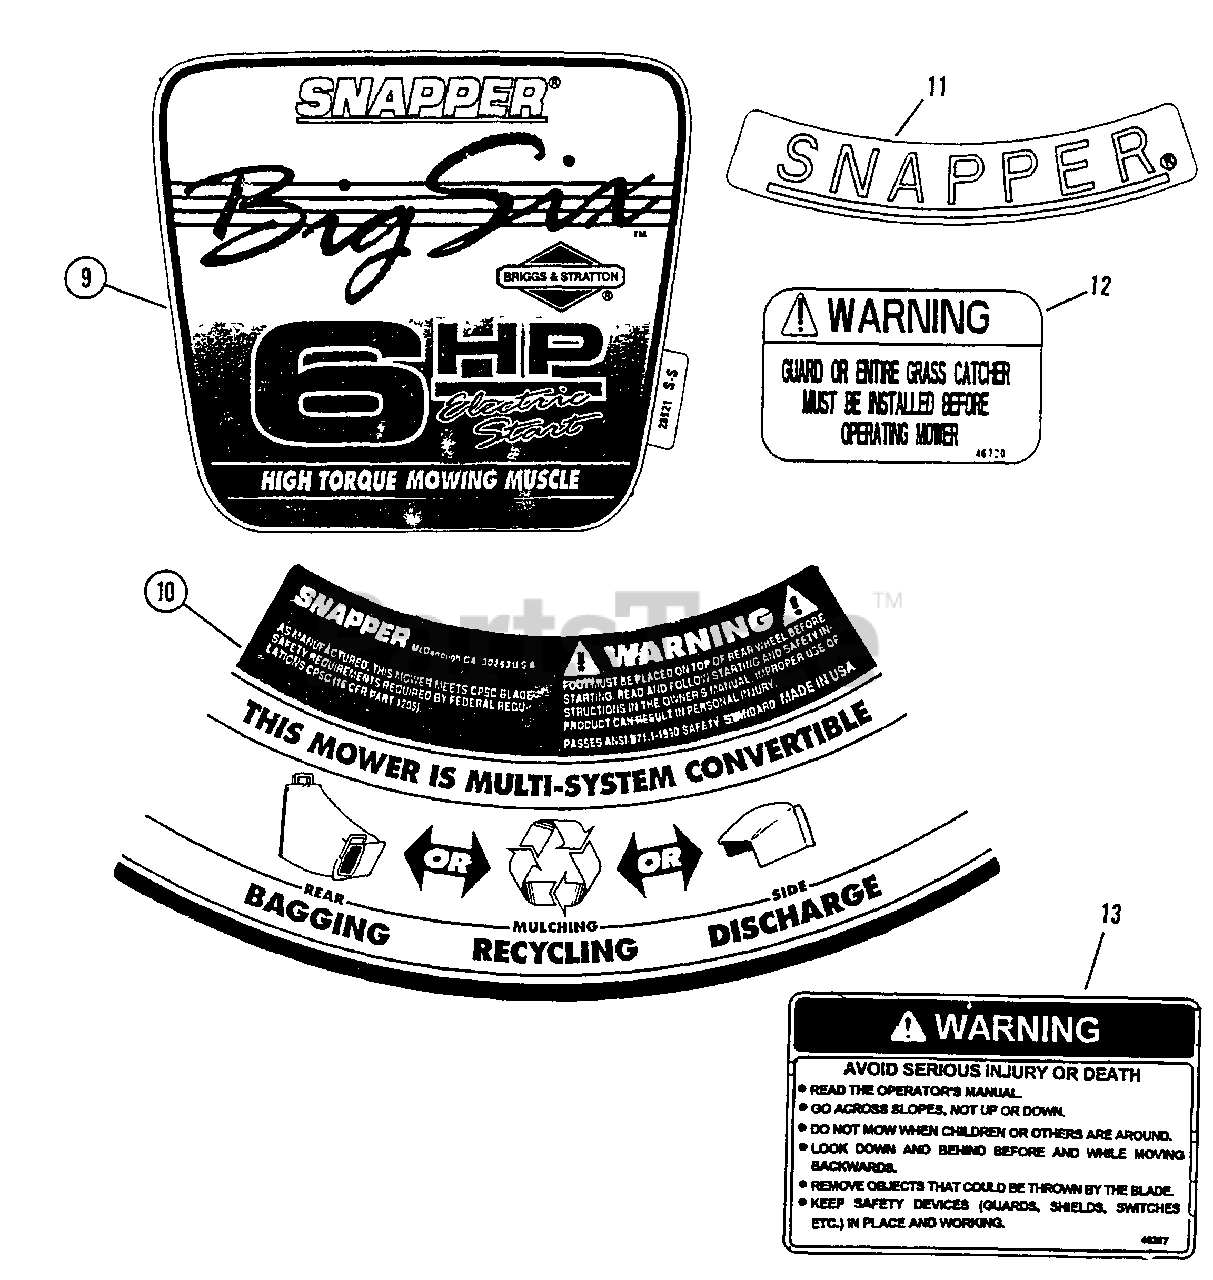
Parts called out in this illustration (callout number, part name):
9	DECAL, Big Six (Electric Start)
10	DECAL, Feature Compliance
11	DECAL, Snapper
12	DECAL, Chute/Deflector
13	DECAL, Warning Instructions
